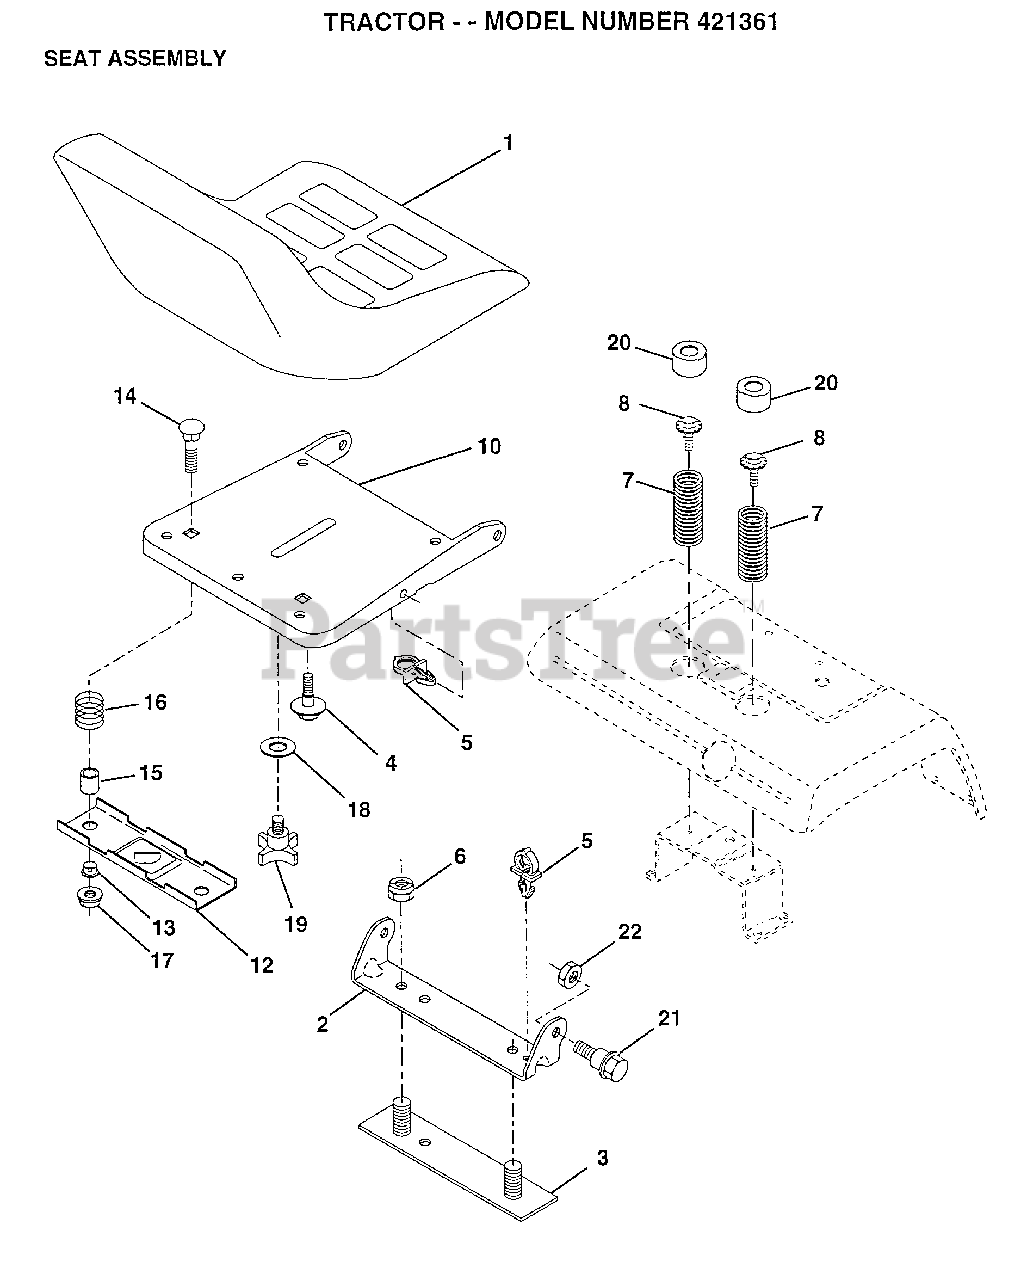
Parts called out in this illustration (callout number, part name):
2	BRACKET PVT SEAT
3	STRAP ASM FENDER
4	"BOLT,SHOULDER"
5	CLIP.PUSH-IN.HING
7	SPRING COMPRESSIO
8	BOLT.5/16-18.UNC
12	BRKT SWITCH
13	BUSHING
15	SPACER SPLIT
16	SPRING COMPRESSED
18	WASHER
19	"KNOB 1/2"" YT"
20	CAP SPRING
21	BOLT.SHLD.5/16-18
